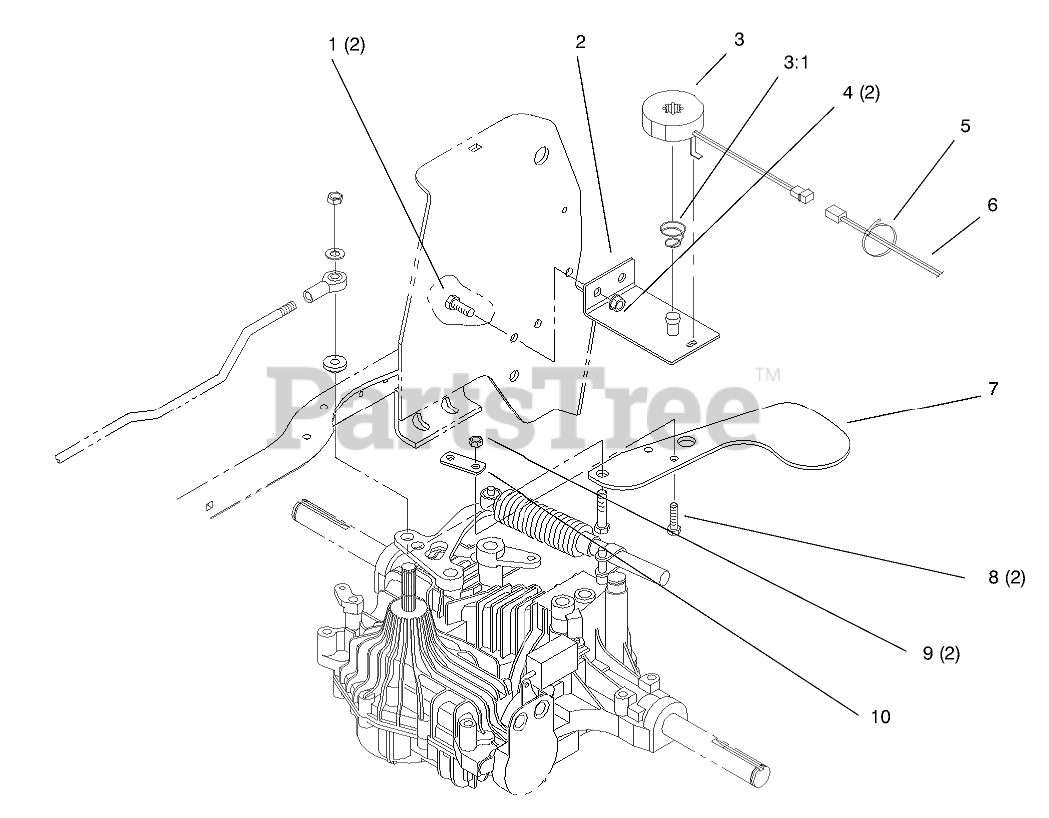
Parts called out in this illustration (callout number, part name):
1	SCREW-HH
2	Cruise Bracket
3	ASM - MAGNET
3:1	SPRING-COMPRESSION
4	NUT-LOCK, NI
6	HARNESS - WIRE
7	ARM - CRUISE
8	SCREW-HH
9	NUT-LOCK, NI
10	CLAMP - CRUISE
